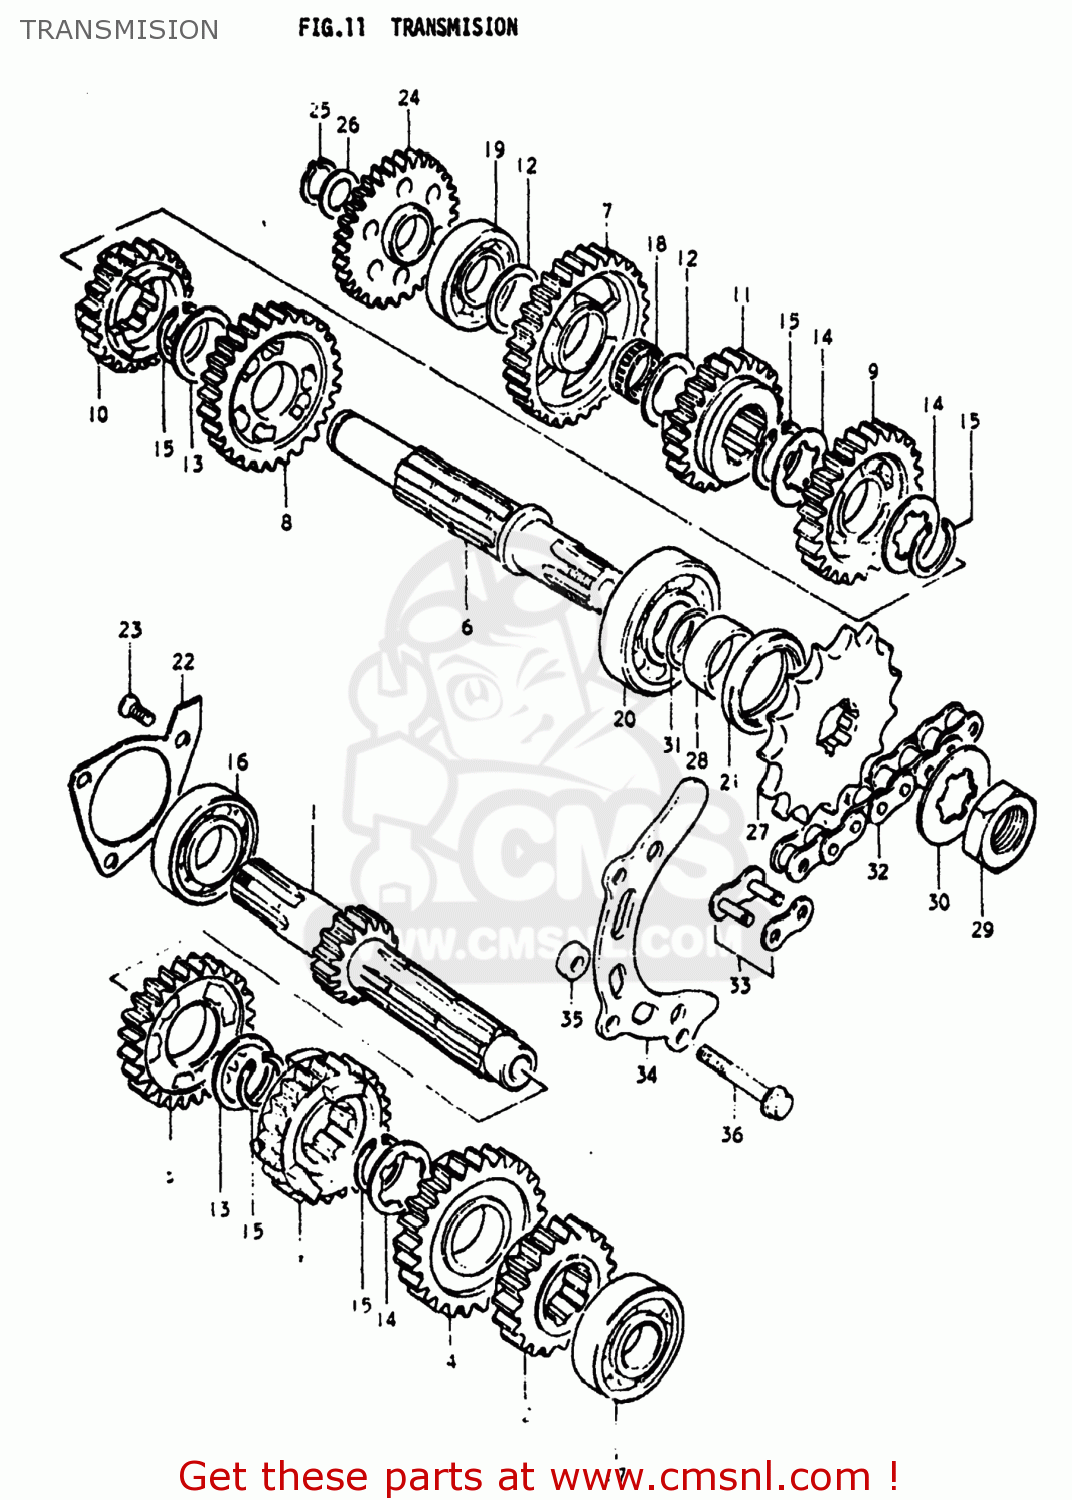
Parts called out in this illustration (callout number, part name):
1	SHAFT,COUNTER
2	GEAR,SECOND DRIVE
3	GEAR,THIRD DRIVE
4	GEAR,FOURTH DRIVE
5	GEAR,FIFTH DRIVE
6	SHAFT,DRIVE
7	GEAR,FIRST DRIVEN
8	GEAR,SECOND DRIVEN
9	GEAR,THIRD DRIVEN
10	GEAR,FOURTH DRIVEN
11	GEAR,FIFTH DRIVEN
12	WASHER
13	SHIM(22X28X0.5)
14	WASHER,LOCK
15	CIRCLIP
16	BEARING
17	BEARING
18	BEARING(17X21X9.8)
19	BEARING
20	BEARING
21	SEAL,OIL(32X42X6)
22	PLATE,COUNTERSHAFT BEARING
23	SCREW
24	GEAR,KICK STARTER IDLE
25	CIRCLIP
26	WASHER
27	SPROCKET,ENGINE
28	SPACER(22X32X11.5)
29	NUT
30	WASHER,LOCK
31	O RING(D:1.7,ID:22)
32	CHAIN ASSEMBLY,DRIVE
33	JOINT ASSEMBLY,CHAIN
34	PLATE,FRONT CHAIN GUIDE
35	SPACER(6.5X14X7.5)
36	BOLT
